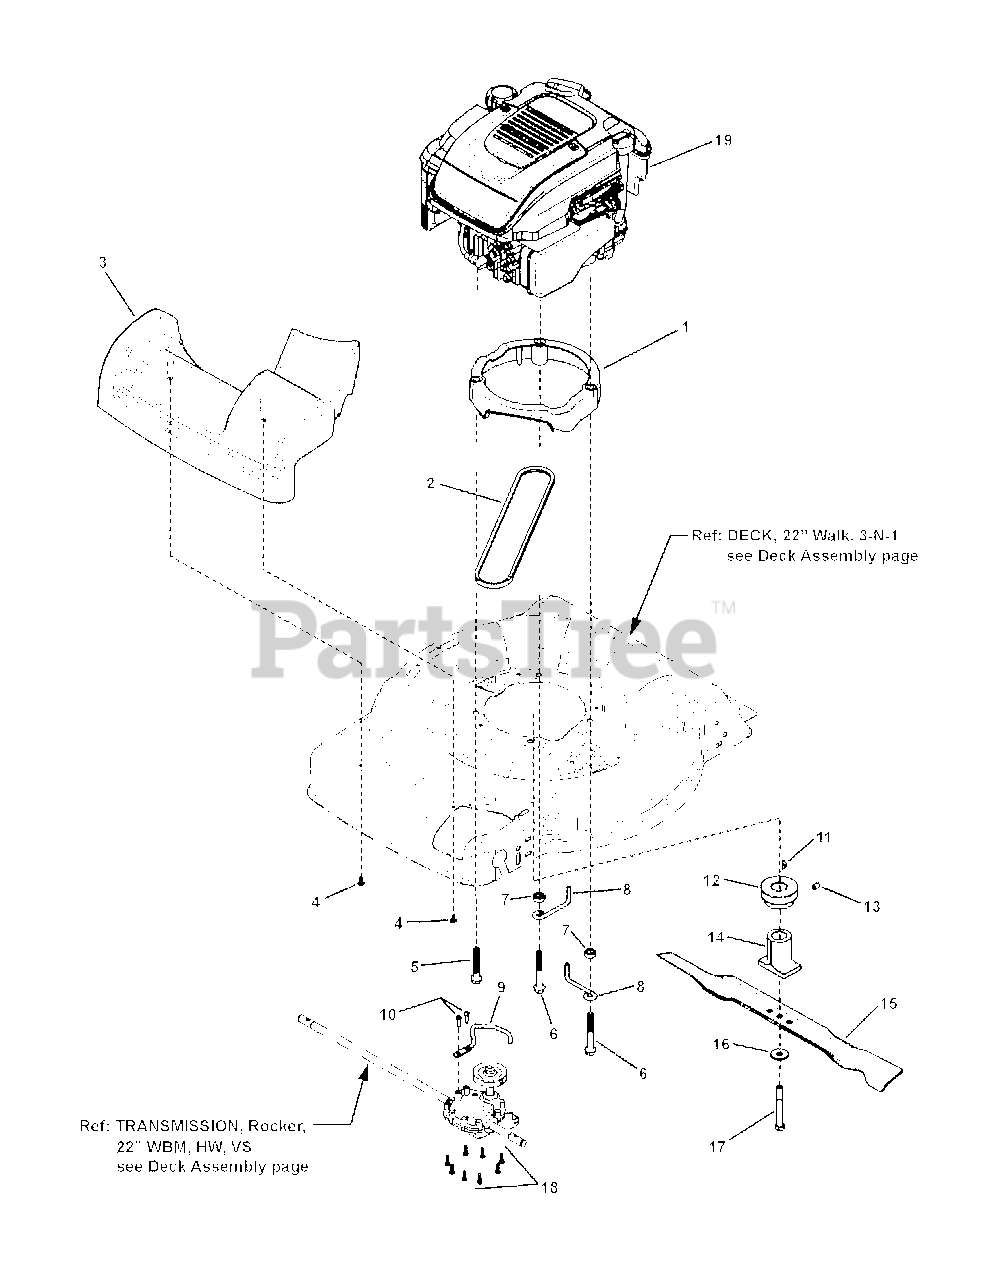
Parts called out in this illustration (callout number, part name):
1	ASSEMBLY, Engine Spacer, 22" WBM, Self-Propelled
2	BELT, Traction Drive, 22 Pivot Handle
3	FRONT COVER, Deck, 22" Front Wheel Drive
4	SCREW, 4.8 x 1.59 x 13mm, Round Washer Head Hi-Lo (Torx)
5	BOLT, 3/8-16 NS x 2-1/2" Hex Head
6	SCREW, 3/8-16 x 3" Hex Washer Self-Tap
7	SPACER, BELT GUIDE, 22" VS
8	BELT GUIDE, Engine, 22" VS
9	BELT GUIDE, Transmission, 22 WBM
10	SCREW, #10-16 x 3/4 Pan Head Self-Tap, Combo
11	KEY, #HP-506 Hi-Pro
12	PULLEY, Engine
13	SET SCREW 5/16-18 x 1/2 Hex Recess
14	BLADE HUB, 22" Deck, Self Propelled
15	BLADE, 22", Walk Mower
16	WASHER, .38" I.D. x 1.183 O.D. Bellville
17	BOLT, 3/8-24 x 3-1/4" Hex Head, GR 8
18	SCREW, 7mm x 1 x .550 AB Point
19	* ENGINE, B&S, 675 Ser, X-Spec, B3
19	* ENGINE, B&S, 675 Ser, X-Spec, F3
19	* ENGINE, B&S, 700 Ser, X-Spec, B3
